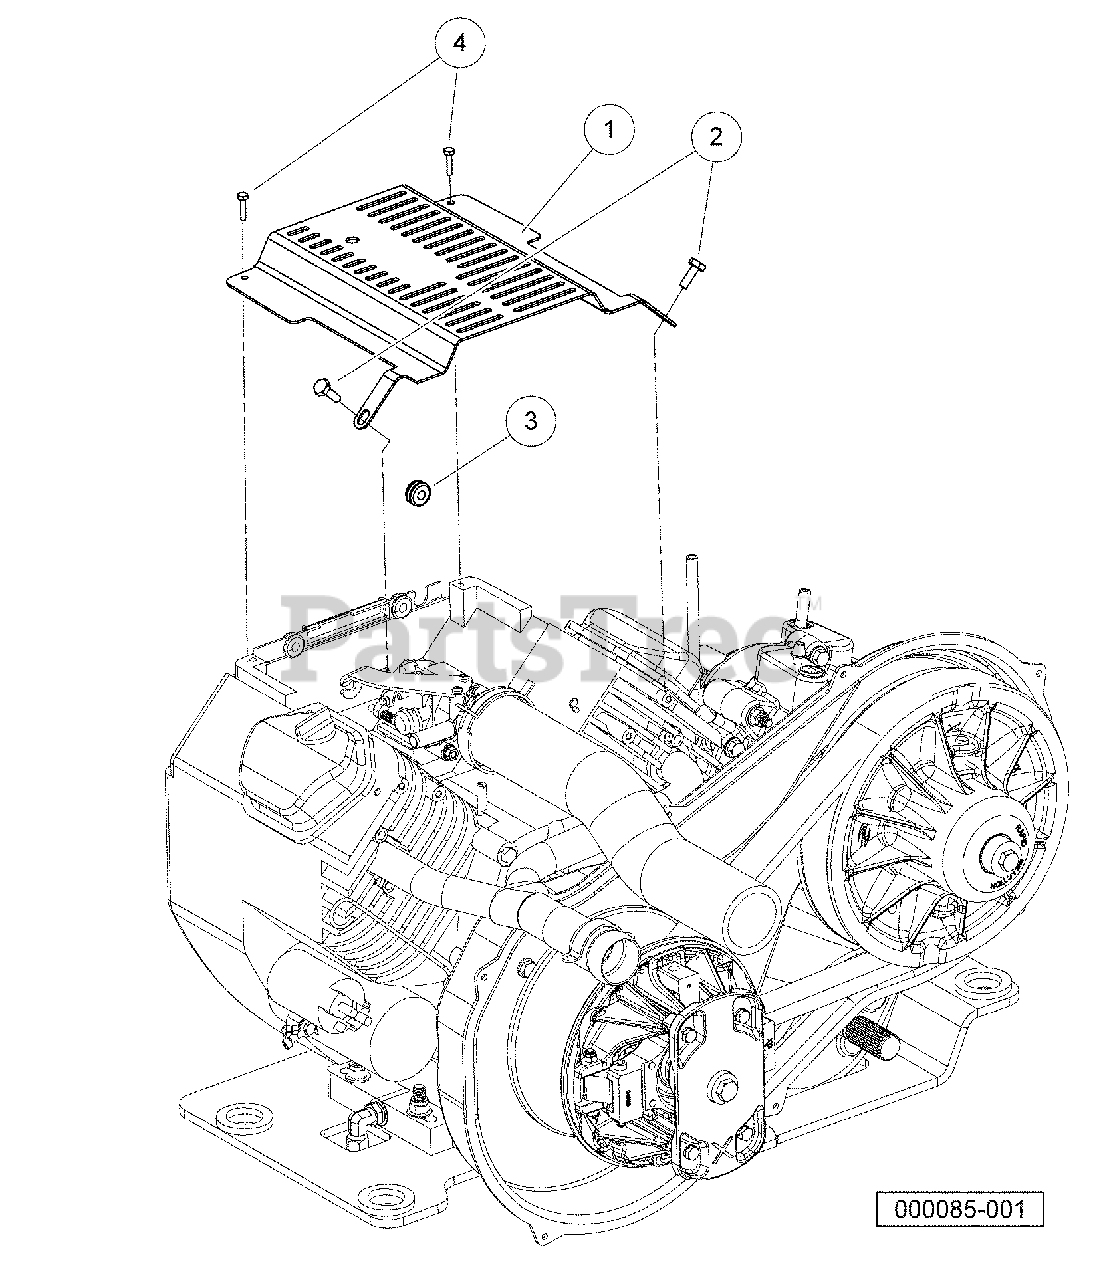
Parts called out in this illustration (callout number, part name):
1	Cover, Engine, Honda
2	Bolt, M8 X 1.25 X 20
3	Grommet, Split, 50 Durometer
4	Bolt, M5 X .8 X 20
